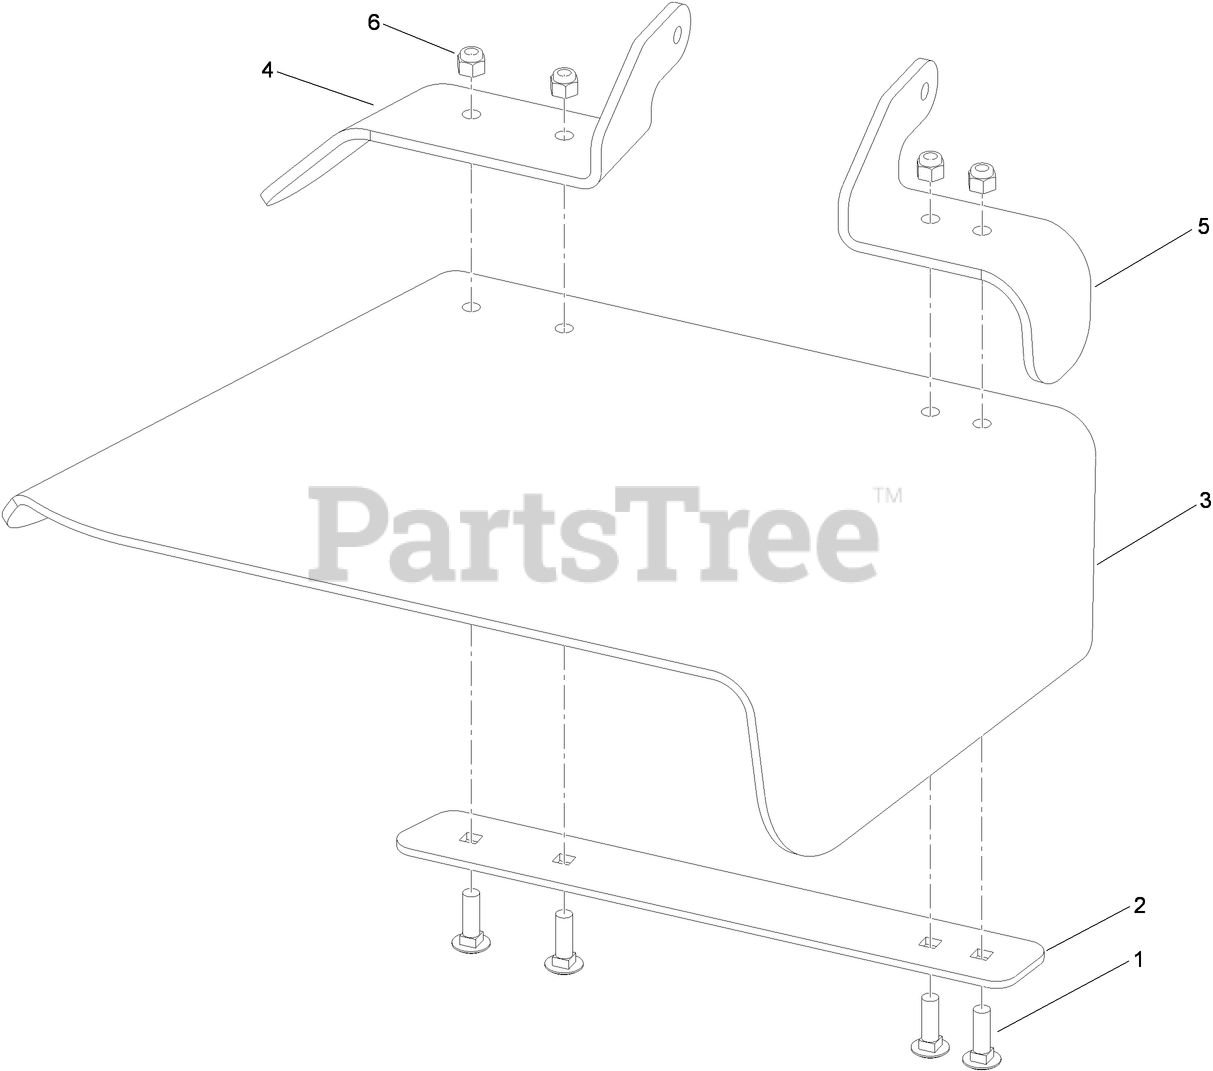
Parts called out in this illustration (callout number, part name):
1	BOLT-CARR
2	STRAP-DISCHARGE
3	DEFLECTOR-RUBBER
4	BRACKET-HINGE, REAR
5	BRACKET-HINGE, FRONT
6	NUT-LOCK, NI
